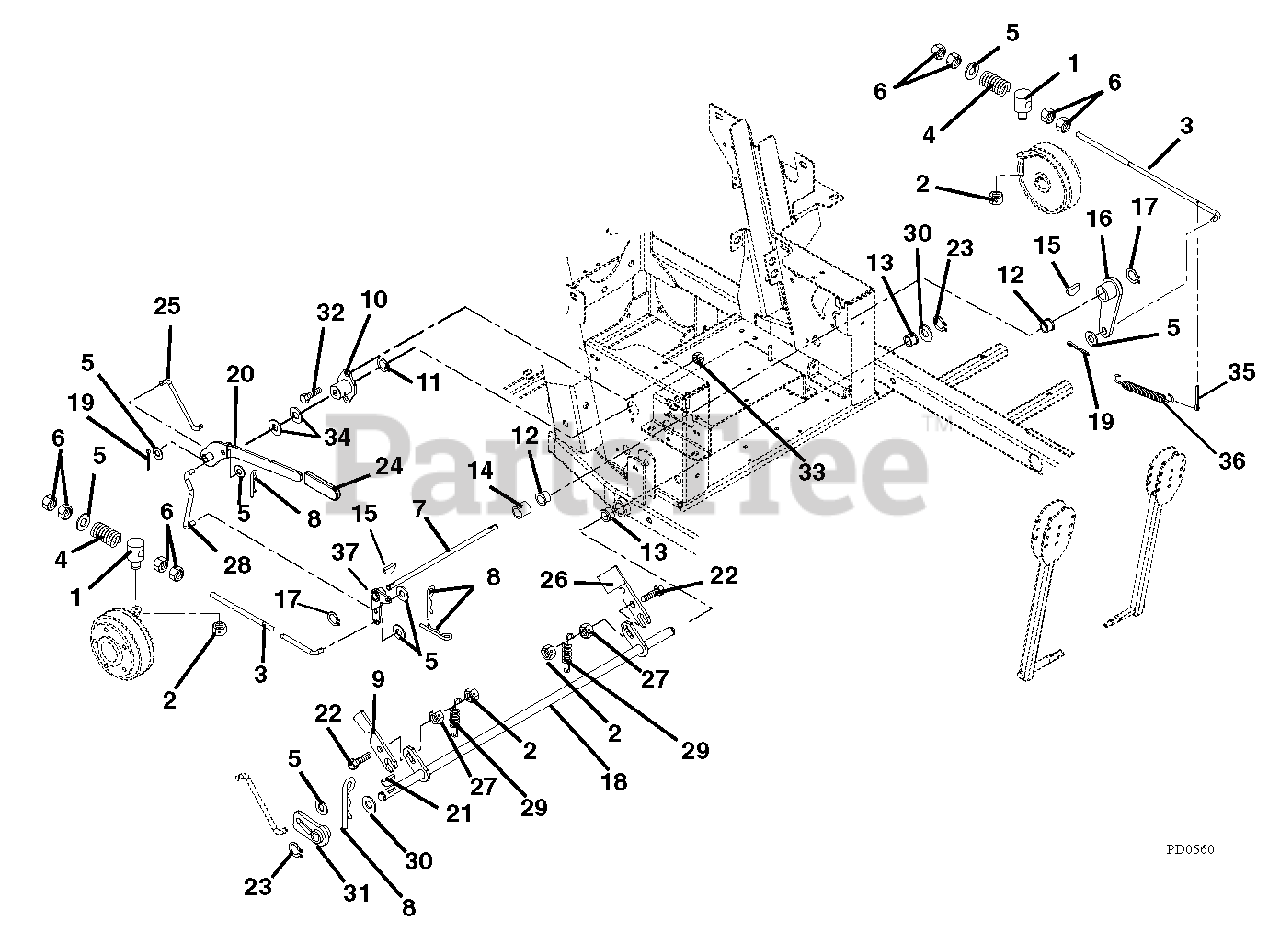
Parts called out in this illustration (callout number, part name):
1	Pivot, Brake Rod
2	Nut, Locking Center .31-18
3	PTO Link Rod
4	Spring, Compression .142 x .710 x 1.75
5	Washer, Flat Steel .406 x .812 x .065
6	Nut, Hex .38-16
7	Shaft, Brake Cross
8	Pin, Hair
9	Slide, Interlocking Brake
10	Bushing, Flange
11	Ring, Retaining External .625 x .05
12	Bushing, Flange Nylon .762 x 1.00 x .58 x 1.48
13	Bushing, Flange .515 x .75 x .745 x 1.00
14	Bushing, Sleeve .75 x 1.00 x .75
15	Key, Woodruff .19 x 1.00 x .19 SAE 8630
16	Arm, Brake
17	Ring, Retaining External .69 x .077
18	Weldment, Mechanical Brake
19	Pin, Cotter External .09 x .75
20	Weldment, Handle
21	Key, Woodruff .13 x .63
22	Bolt, Round Head Square Neck .31-18 x 1.25 Grade 5
23	Ring, Retaining External .50 x .05
24	Grip, Handle
25	Linkage, Brake Actuating
26	Interlock, Safety Switch
27	Nut, Locking Top Flange .31-18
28	Linkage, Brake Actuating
29	Spring, Tension .048 x .44 x 1.75
30	Washer, Flat Steel .505 x 1.00 x .062
31	Weldment, Parking Brake Hub
32	Bolt, Hex .31-18 x .75 Grade 5
33	Nut, Locking Top Flange .31-18
34	Washer, Flat Steel .630 x 1.25 x .062
35	Pin, Cotter .12 x .75 Extended Prong Square Cut
36	Spring, Extension
37	Weldment, 200 Brake ACT. Arm
